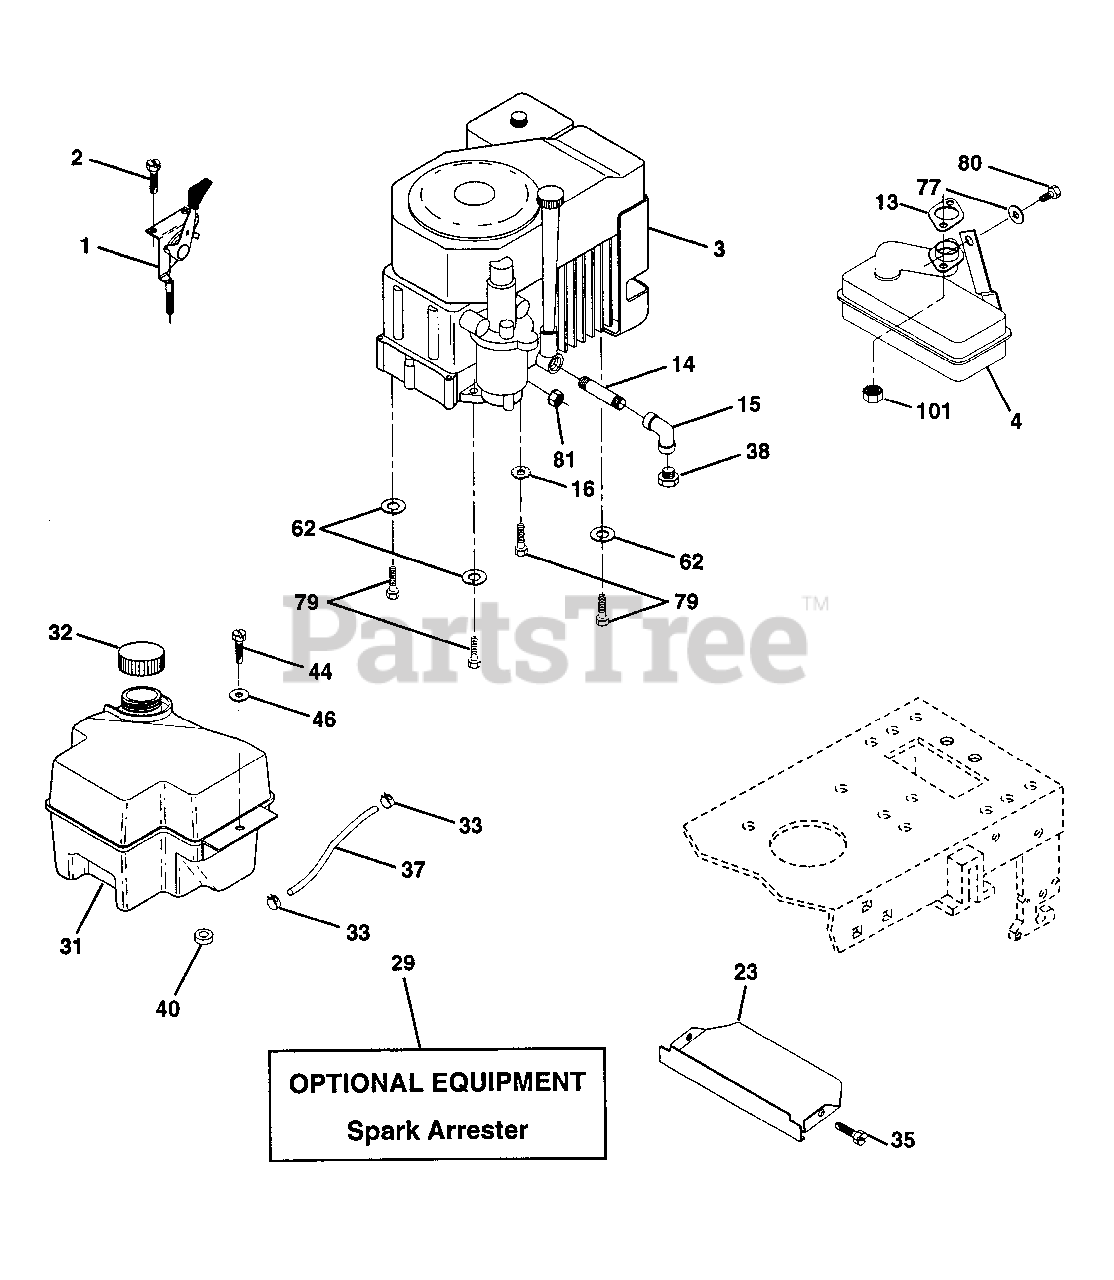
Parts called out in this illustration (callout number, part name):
1	Control THTICH 27 LH FLAG DOM
2	Screw Hex Thd Cut 1/4-20 x 5/8 T
4	Muffler
13	Gasket Kohler CV13-CV16.5
14	Nipple Pipe 3/8 Npt X 3-1/2
15	Elbow Std 90 Degree 3/8-18 Npt
16	Washer Lock Ext Tooth 5/16
23	Shield Browning/Debris Guard
29	Kit Spark Arrestor (Flat Scrn)
31	Tank Fuel Front 2 00 Gal Nat
32	Cap Asm Fuel W/sym Vented
33	Clamp Hose Black
35	Screw
37	Line Fuel 20"
38	Plug Oil Drain
40	Bushing Snap Nyl Blk Fuel Line
44	Screw Hexwsh Thdrol 1/4-20 x 3/4
46	Washer 9/32 X 7/8 X 16 Ga
62	Washer Lock Hvy Hlcl Spr 5/16
77	Washer 5/16 x 3/4 x 16 Ga.
79	Bolt Hex
80	Bolt Hex Hd 5/16-18 UNC x 1/2
81	Nut Flange 1/4-20 Starter Nut
101	Nut Flange Me-1.25 Non-LK
